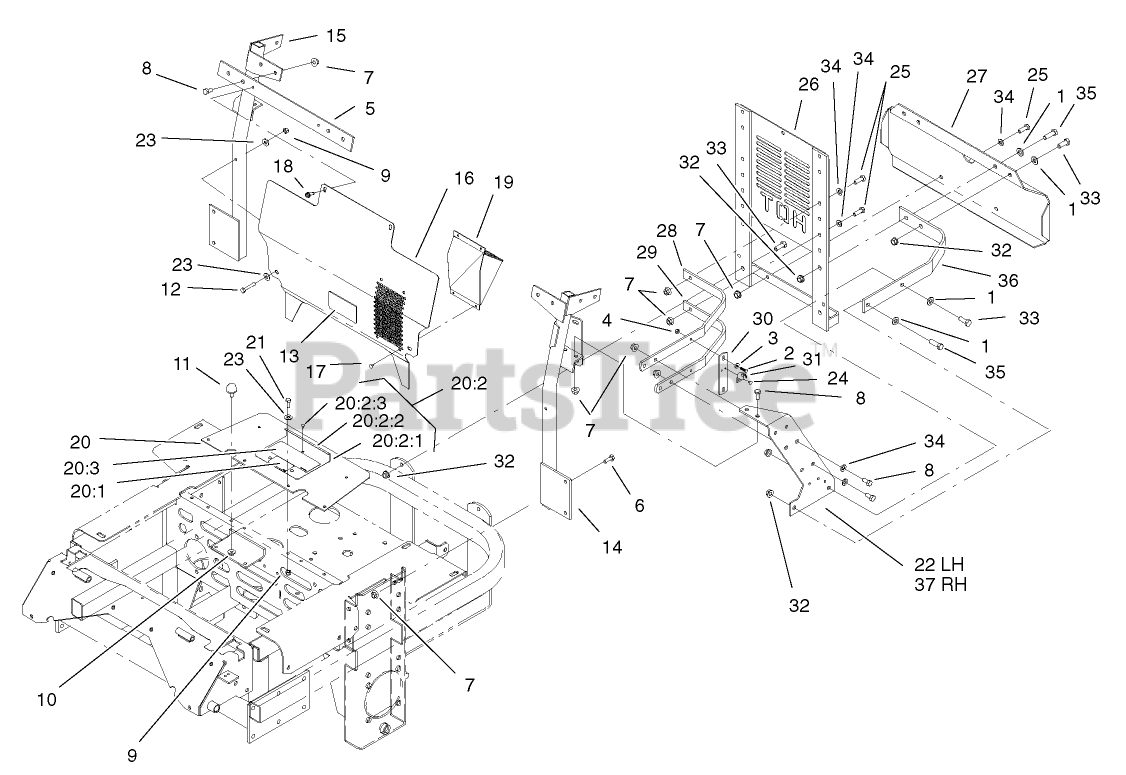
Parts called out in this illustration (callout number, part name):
1	WASHER-FLAT
2	SCREW
3	WASHER-FLAT
4	NUT-LOCK, NI
5	CROSSBAR
6	SCREW-HH
7	NUT-HF
8	SCREW-HH
9	NUT-LOCK, NI
10	NUT-HF
11	BUMPER
12	SCREW-HH
13	DECAL-ROUTING, BELT
14	Brace-Radiator, LH
15	BRACE-RADIATOR, RH
16	Deflector-Air
17	RIVET-POP
18	SCREW-HWHTF
19	Plenum-Intake, Air
20	SHIELD ASM
20:1	DECAL-IMPORTANT
20:2	SHIELD AND LIFT ASM
20:2:1	SHIELD-ENGINE
20:2:2	LIFT-SHIELD
20:2:3	RIVET-POP
20:3	DECAL-DEVICES, ROTATING
21	SCREW-HH
22	PLATE-SIDE, LH
23	WASHER-FLAT
24	RIVET
25	SCREW-HH
26	MOUNT-RADIATOR, REAR
27	GUARD-BUMPER
29	RIB-BOTTOM
30	BAR-HOOK, LATCH
31	KEEPER-LATCH, RUBBER
32	NUT-HHF, WHIZ
33	SCREW-HH
34	WASHER-PLAIN
35	SCREW-HH
36	BAR-RADIATOR MOUNT FRAME
37	PLATE-SIDE, RH
